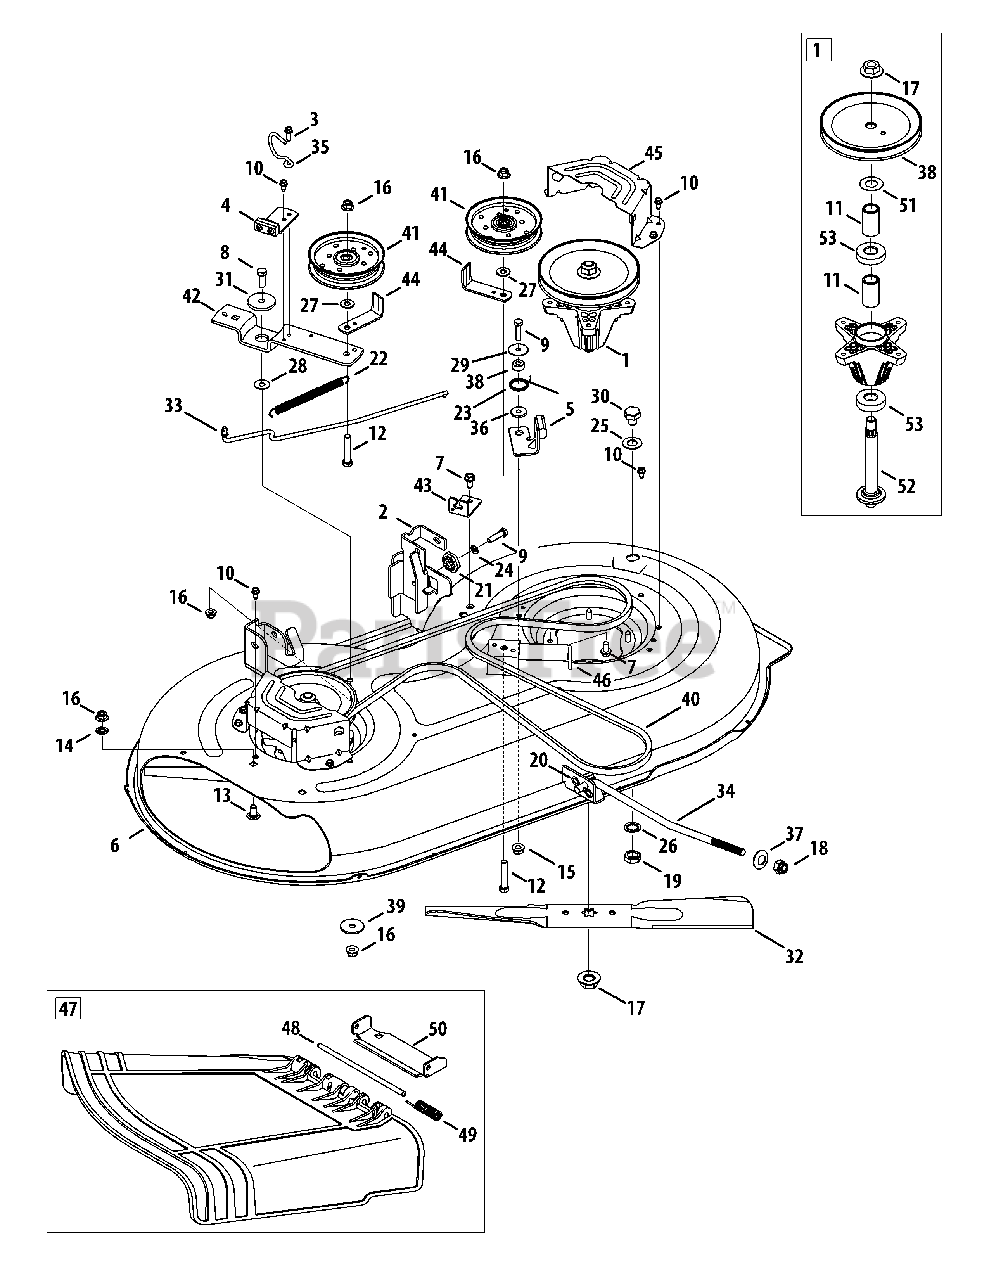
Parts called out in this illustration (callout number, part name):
1	Spindle Pulley Assembly
2	Deck Hanger Bracket Assembly
3	Screw, 1/4-20 x .750
4	Brake Assembly
5	Brake Assembly
6	Deck
7	Screw, 5/16-18 x .750
8	Screw, 3/8-16 x 1.25
9	Hex Screw, 5/16-18 x 1.25
10	Screw, 1/4-20 x .500
11	Spacer, .792 x 1.060 x 1.860
12	Hex Head Screw, 3/8-16
13	Carriage Bolt, 3/8-16 x .75
14	Push Nut, 3/8
15	Flangelock Nut, 5/16-18
16	Flangelock Nut, 3/8-16
17	Flange Nut, 5/8-18
18	Flangelock Nut, 1/2-13
19	Hex Nut, M16 - 1.5
20	Cotter Pin, Bow-Tie
21	Deck Adjuster Gear
22	Extension Spring, .62 x 6.12
23	Torsion Spring, 1.0 x 1.17
24	Lock Washer, 5/16
25	Flat Washer, .64 x 1.24 x .06
26	Flat Washer, .5/8 Int. Tth.
27	Flat Washer, .385 x .870 x .092
28	Flat Washer, .385 x 1.0 x .030
29	Flat Washer, .330 x 1.25 x .06
30	Bolt Plug, M16 x 1.5
31	Shoulder Spacer, .8840 x .190
32	Cutting Blade, 21.23": 2 in 1
33	Brake Control Rod
34	Deck Lift Rod
35	Belt Keeper Rod
36	Shoulder Spacer
37	Deck Lift Pivot Cup
38	Deck Pulley, 6.3 dia.
39	Flat Washer, .406 x 1.50 x .105
40	V-Type Belt, 96.5
41	Idler Pulley, 4.25 Diameter
42	Idler Pivot Bracket
43	Deck Cable Engagement Bracket
44	Belt Pulley Guard
45	Deck Belt Cover
46	Deck Support Bracket
47	Chute Deflector Assembly
48	Hinge Pin
49	Torsion Spring, .44 x 2.0
50	Chute Bracket
51	Flat Washer, .760 x 1.50
52	Spindle Shaft
53	Ball Bearing, .787 x 1.85 x .551
